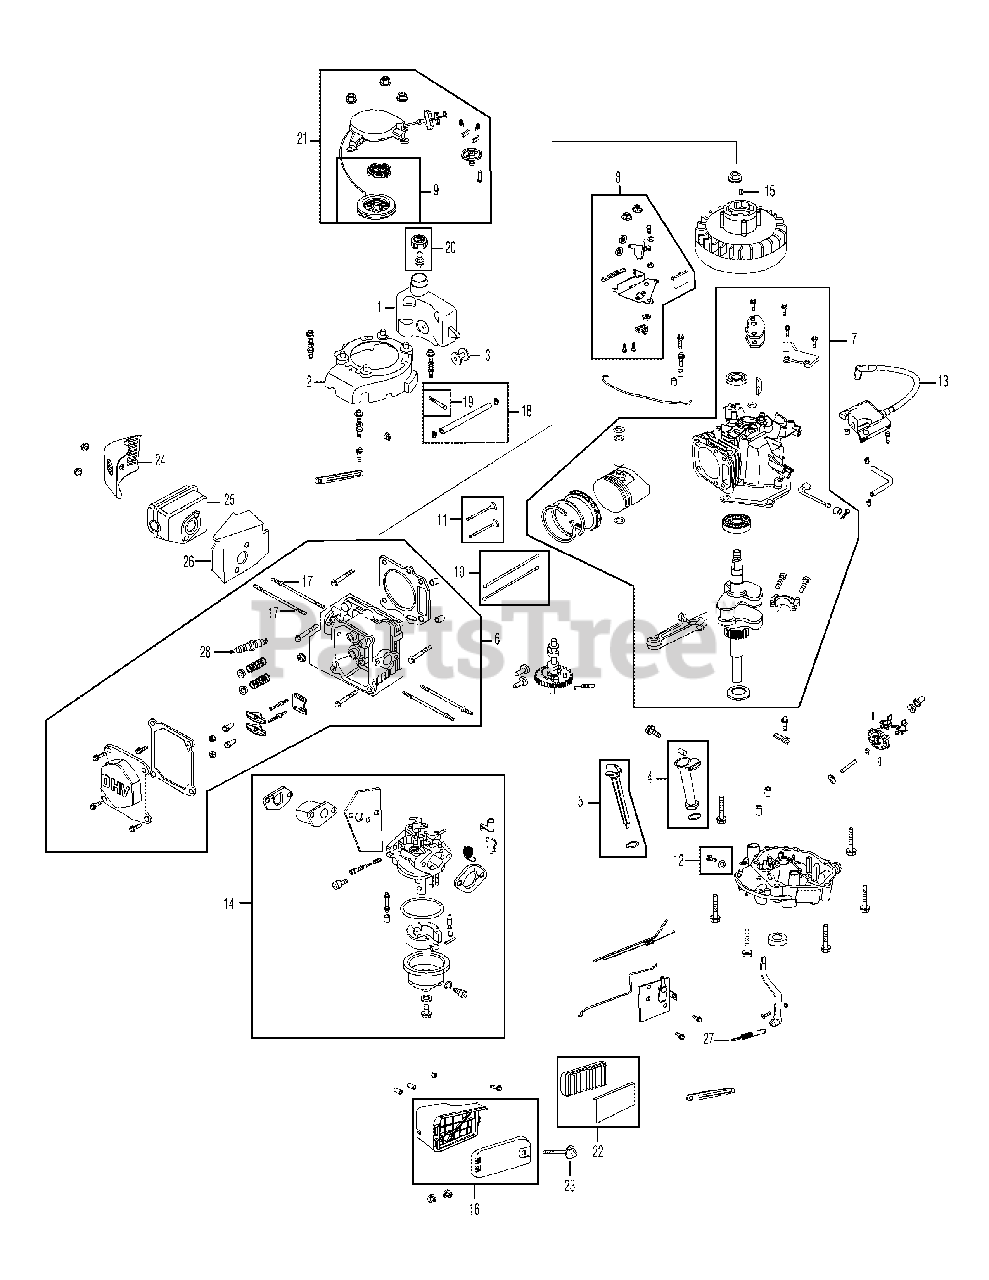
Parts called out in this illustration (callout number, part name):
1	Fuel Tank
2	Flywheel Shroud
3	Rubber Fuel Tank Mounting Washer
4	Oil Filler Tube Assembly
5	Dipstick Assembly
6	Cylinder Head Complete
7	Short Block Assembly
8	Stop Switch and Brake Assembly
9	Recoil Spring and Pulley Assembly
10	Push Rod Kit
11	Valve Kit
12	Oil Drain Plug and Washer Assembly
13	Ignition Coil
14	Carburetor Assembly
15	Flywheel Key
16	Air Cleaner Housing Assembly Complete
17	Muffler Stud Assembly
18	Fuel Line Kit - Inc. hoses, clamps & filter
19	Fuel Filter
20	Fuel Cap Assembly
21	Recoil Starter Assembly
22	Air Cleaner Kit
23	Air Cleaner Thumb Screw
24	Muffler Guard
25	Muffler
26	Muffler Gasket /Heat Shield
27	Governor Return Spring
28	Spark Plug
